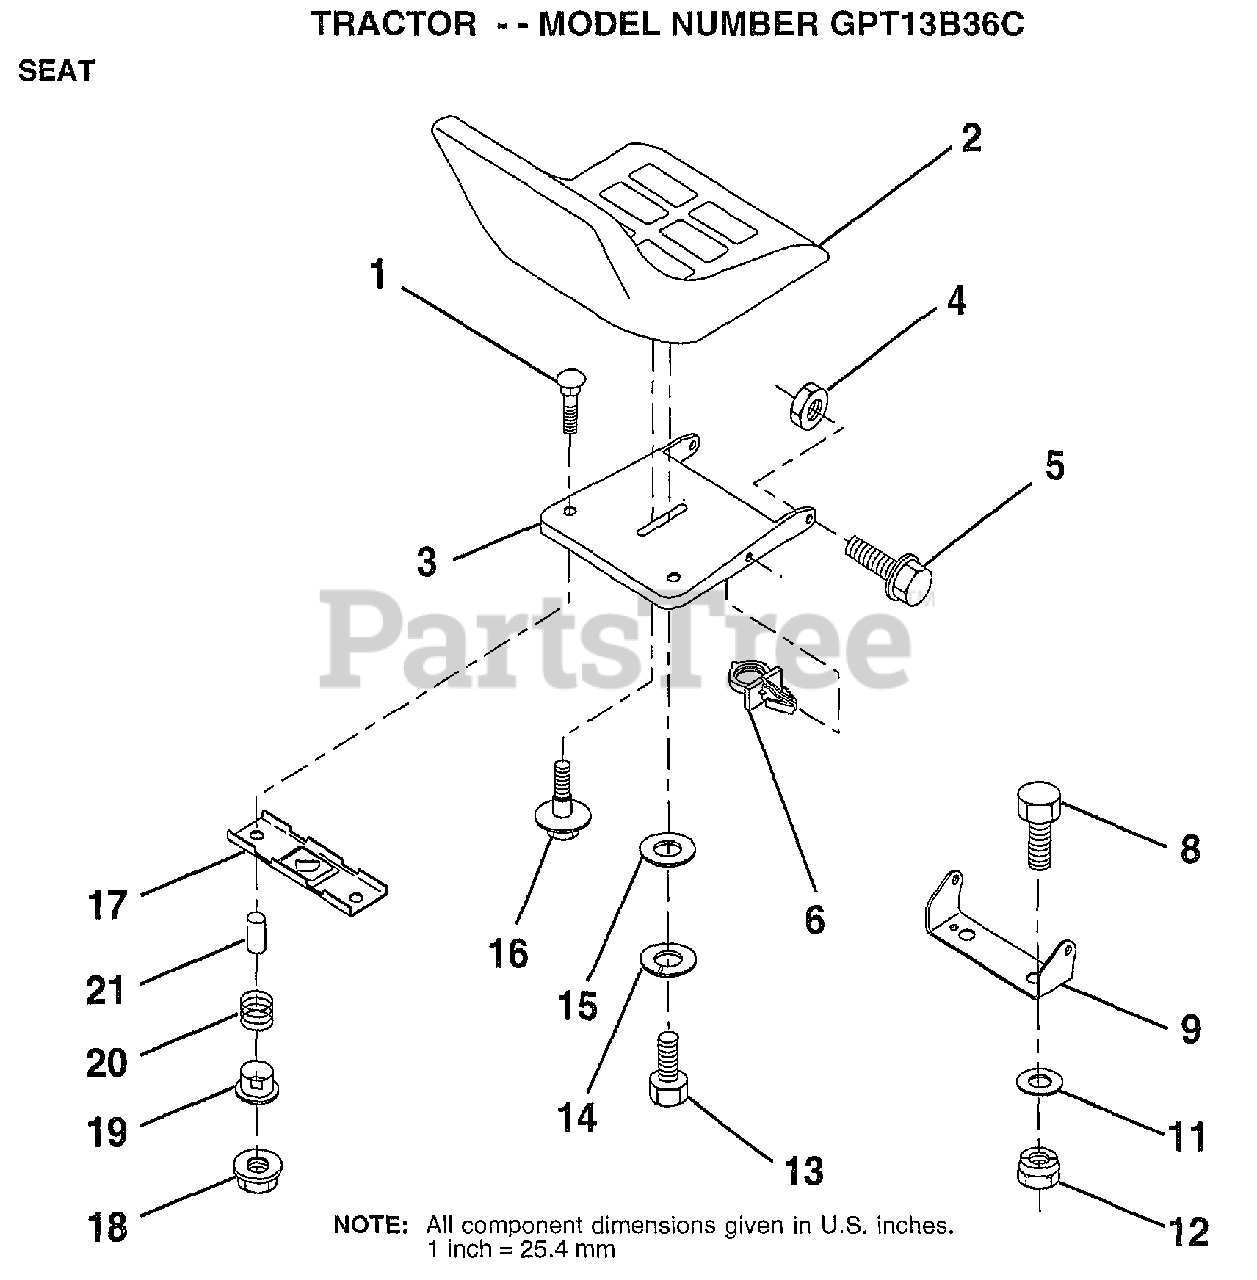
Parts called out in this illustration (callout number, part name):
1	BOLT-RD HD SQ NK
3	PAN-SEAT
4	NUT
5	"BOLT,SHOULDER"
6	CLIP.PUSH-IN.HING
8	BOLT
9	BRACKET PVT SEAT
11	WASHER
12	NUT
13	BOLT
14	LOCKWASHER
15	WASHER
16	"BOLT,SHOULDER"
17	BRKT SWITCH
19	BUSHING
20	SPRING
21	SPLIT SPACER
